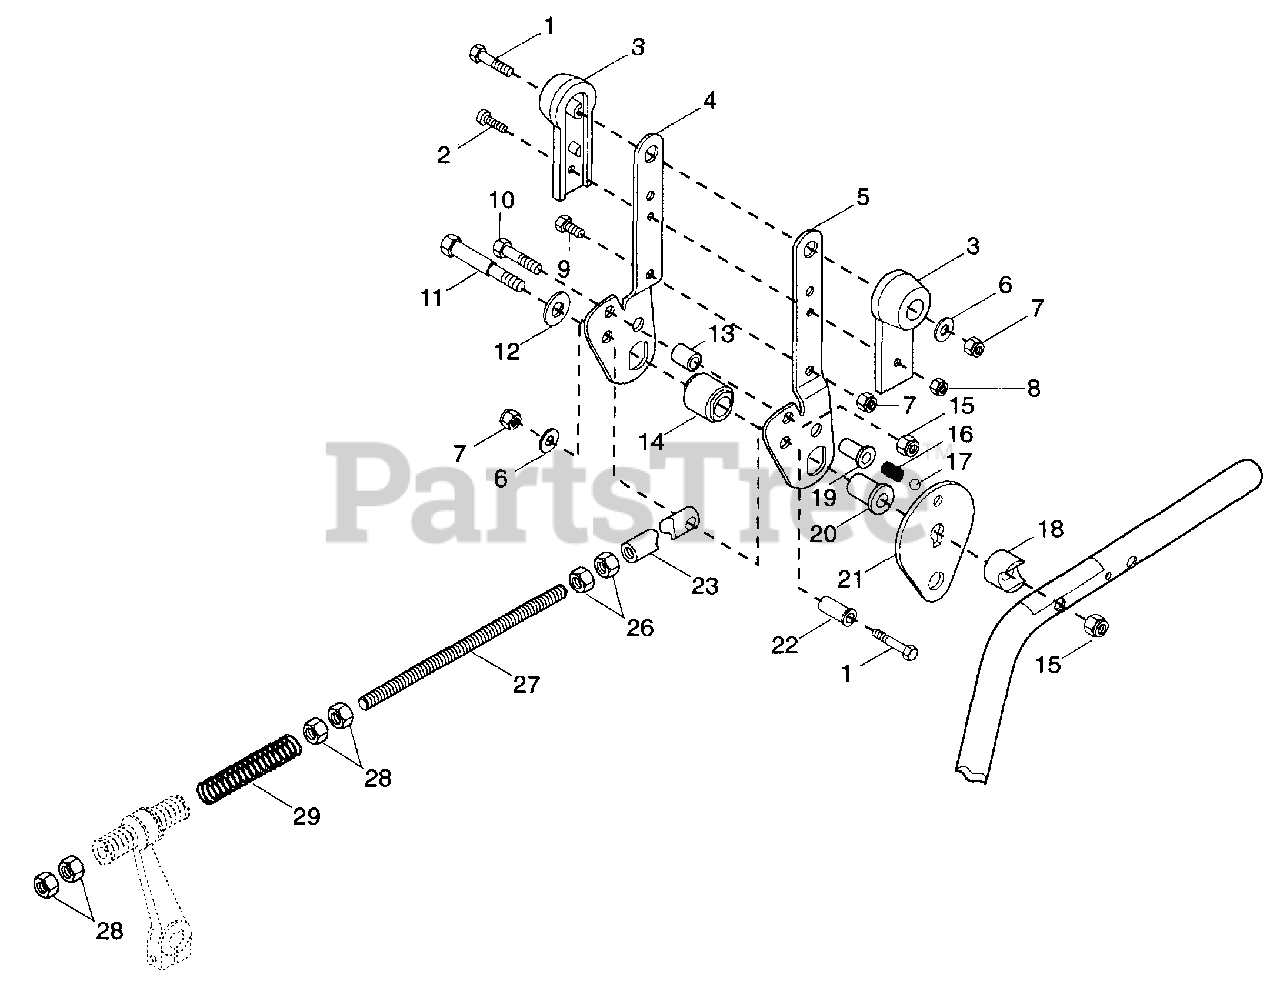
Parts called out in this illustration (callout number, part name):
1	Bolt-Hex .25-20 x 1.50 Grade 5
2	Screw-Machine 6-32 x .625
3	Knob, Handle Control
4	Handle, Control Right Hand
5	Handle, Control Left Hand
6	Washer-Flat-Steel .281 x .620 x .065
7	Nut-Locking-Nylon .250-20
8	Nut-Locking-Machine 6-32
9	Bolt-Hex .25-20 x .63
10	Bolt-Hex .38-16 x 1.50 Grade 5
11	Bolt-Hex .38-16 x 3.5
12	Washer-Flat-Steel .531 x 1.062 x .095
13	Sleeve, Handle Stop
14	Bushing, Flange .751 x 1.13 x 1.07
15	Nut-Locking-Nylon .375-16
16	Spring-Compression .038 x .281 x .88
17	Ball, .312
18	Bracket, Handle Pivot
19	Bushing-Flange .320 x .750 x 1.280
20	Bushing-Flange .515 x .746 x 1.290 x 1.000
21	Plate, Neutral
22	Bushing-Flange .257 x .38 x 1.080
23	Rod, Control Forward-Reverse
24	Nut-Hex .375-16
25	Rod, Extension
26	Nut-Jam .375-16
27	Spring-Compression .072 x .561 x 2.50
